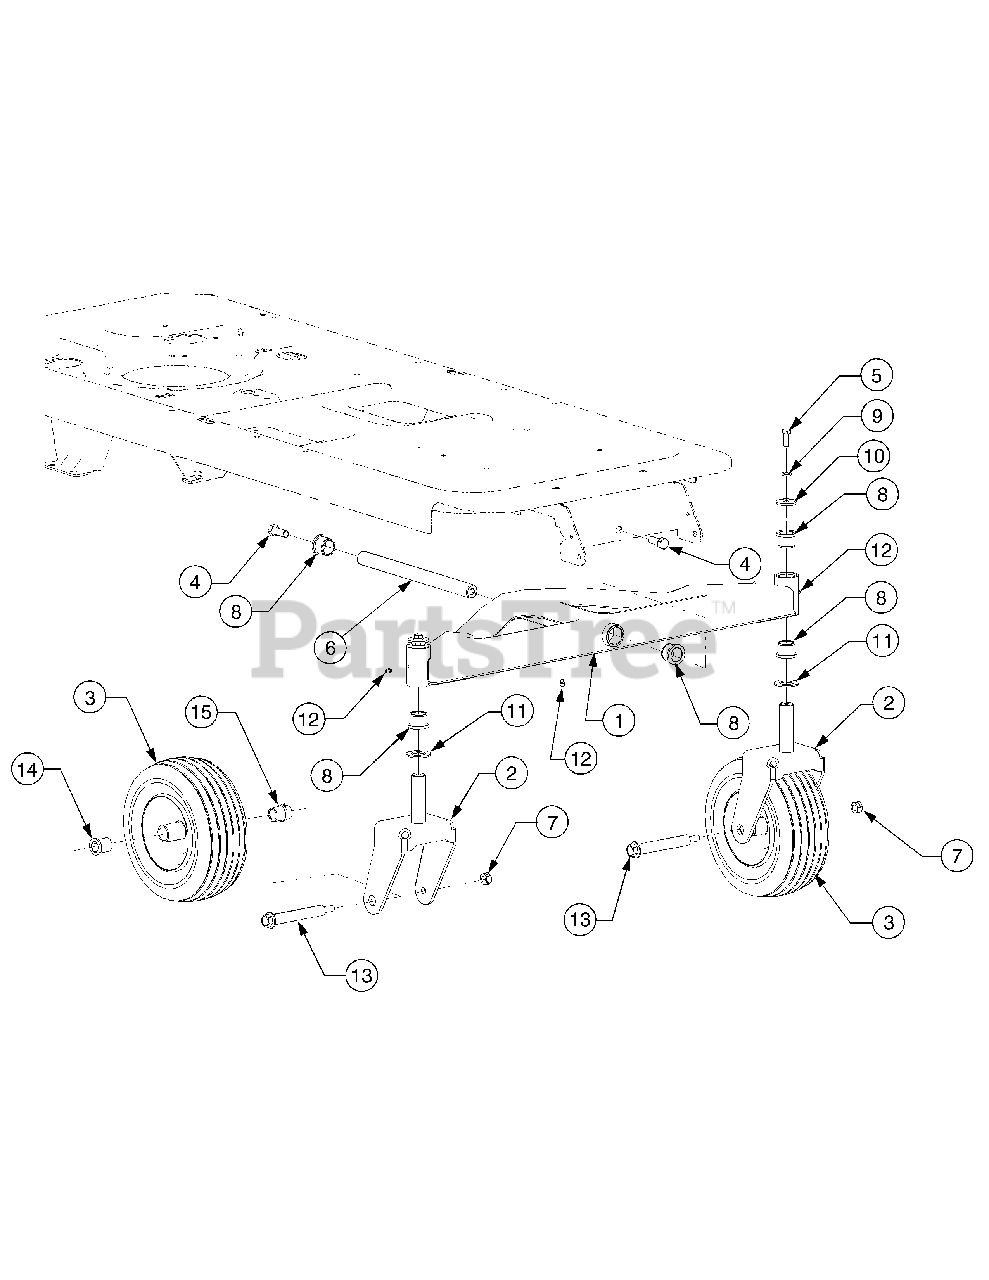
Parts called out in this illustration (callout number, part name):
3	Wheel Assembly, 11.0 x 4- 5.0
4	Screw, Hex Lock, 1/2-13 x 1.25 GR5
5	Screw, Hex Cap, 3/8-16 x 1.0 GR5
6	Shaft, Axle
7	Nut, Hex Lock, 1/2-13 GRB
8	Bearing, Flange, 1.0 x 1.246
9	Washer, Lock, 3/8
10	Washer, Flat, .39 x 1.5 x .134
11	Washer, Flat, 1.0 x 1.75 x .107
12	Fitting, Lube, 3/16 Drive
13	Screw, Shoulder, .75 x 4.75:7/16-14
14	Bearing, Flange, .76 x 1.0 x 1.2
15	Bearing, Flange, .76 ID w/Lube Ftg.
